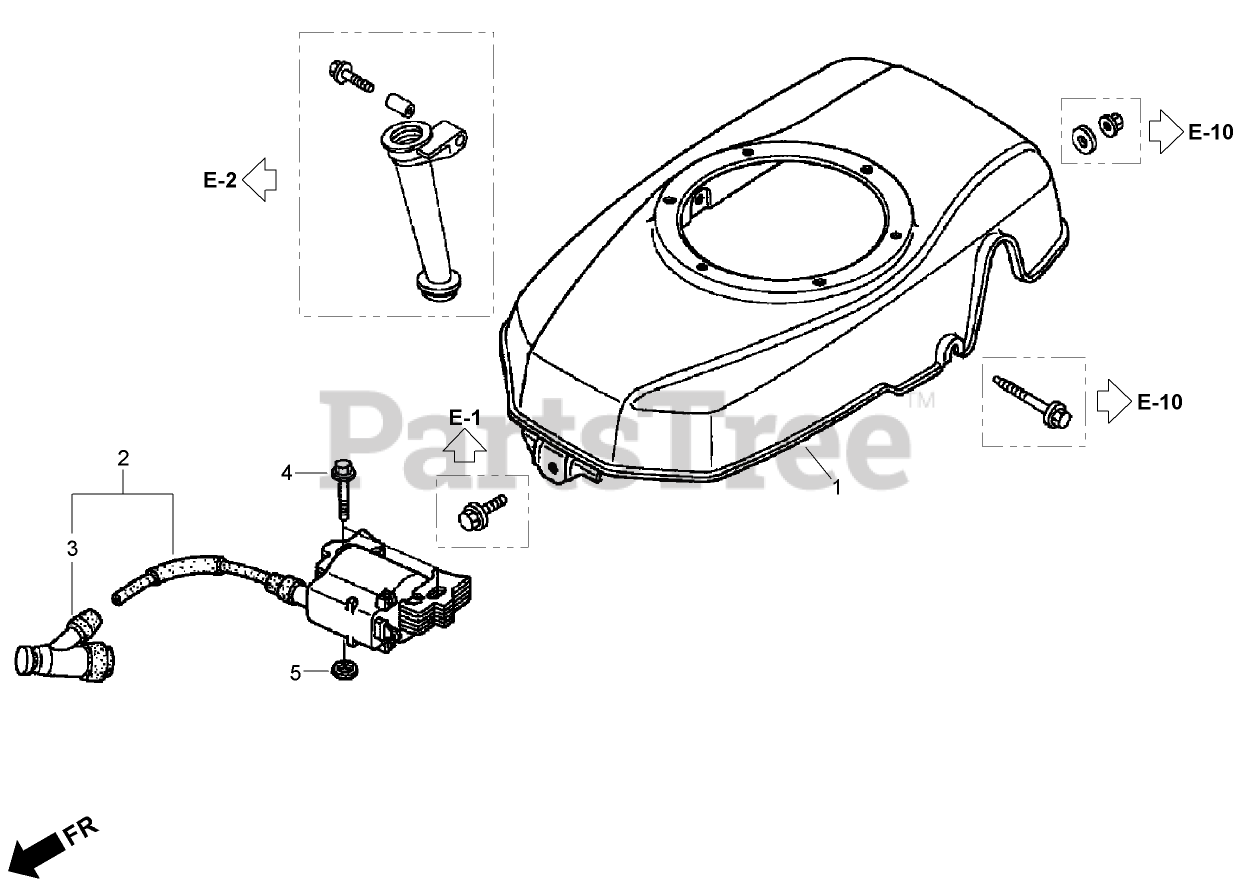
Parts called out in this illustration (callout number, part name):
1	COVER-FAN (N H1) (BLACK)
2	IGNITION COIL ASM
3	NOISE SUPPRESSOR CAP ASM
4	BOLT-FLANGE (6X28) (C T200) (engine serial numbers starting at 6901761)
5	WASHER-PLAIN (6 mm)
